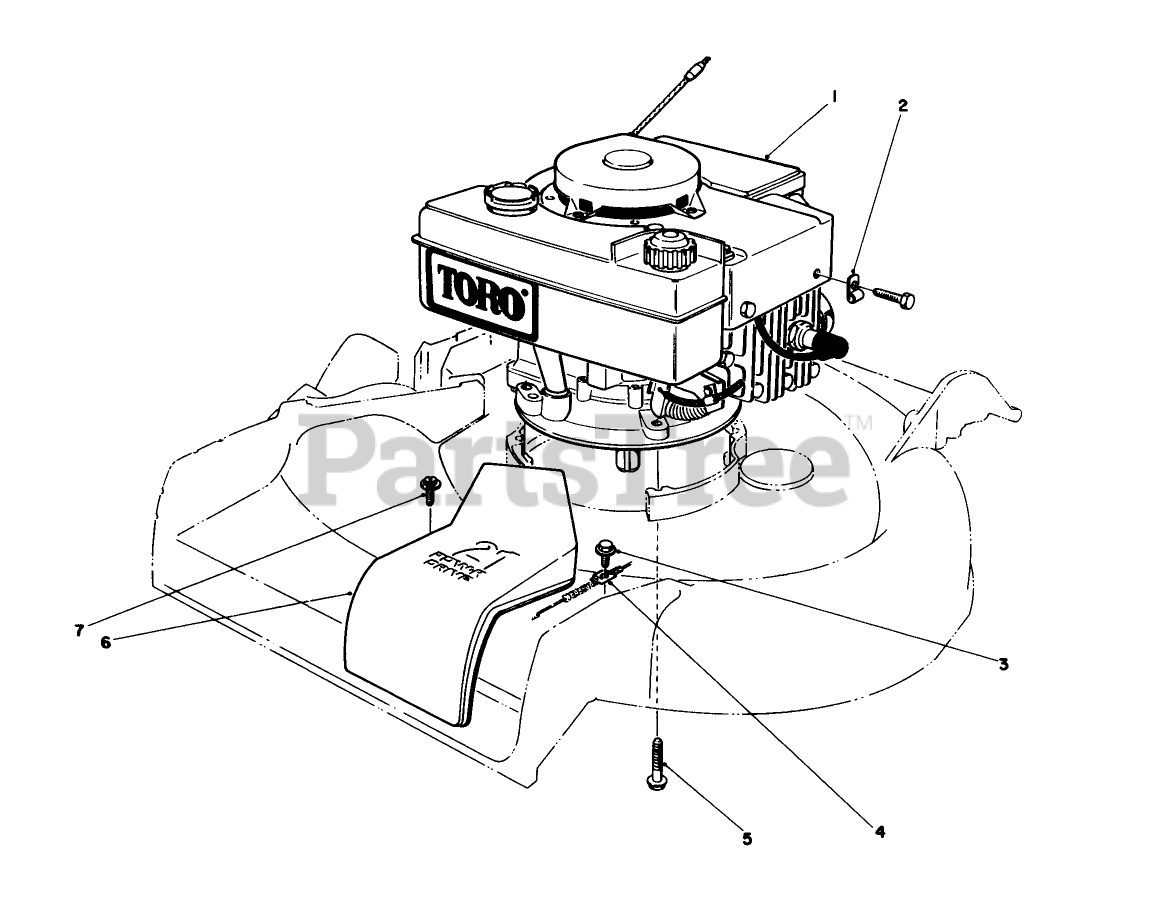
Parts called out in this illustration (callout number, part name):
1	Engine
3	SCREW-THD ROLL, HWH
5	3/8-16 X 2-3/4 CAPSCR
6	BELT COVER 21" S D
7	SCREW
